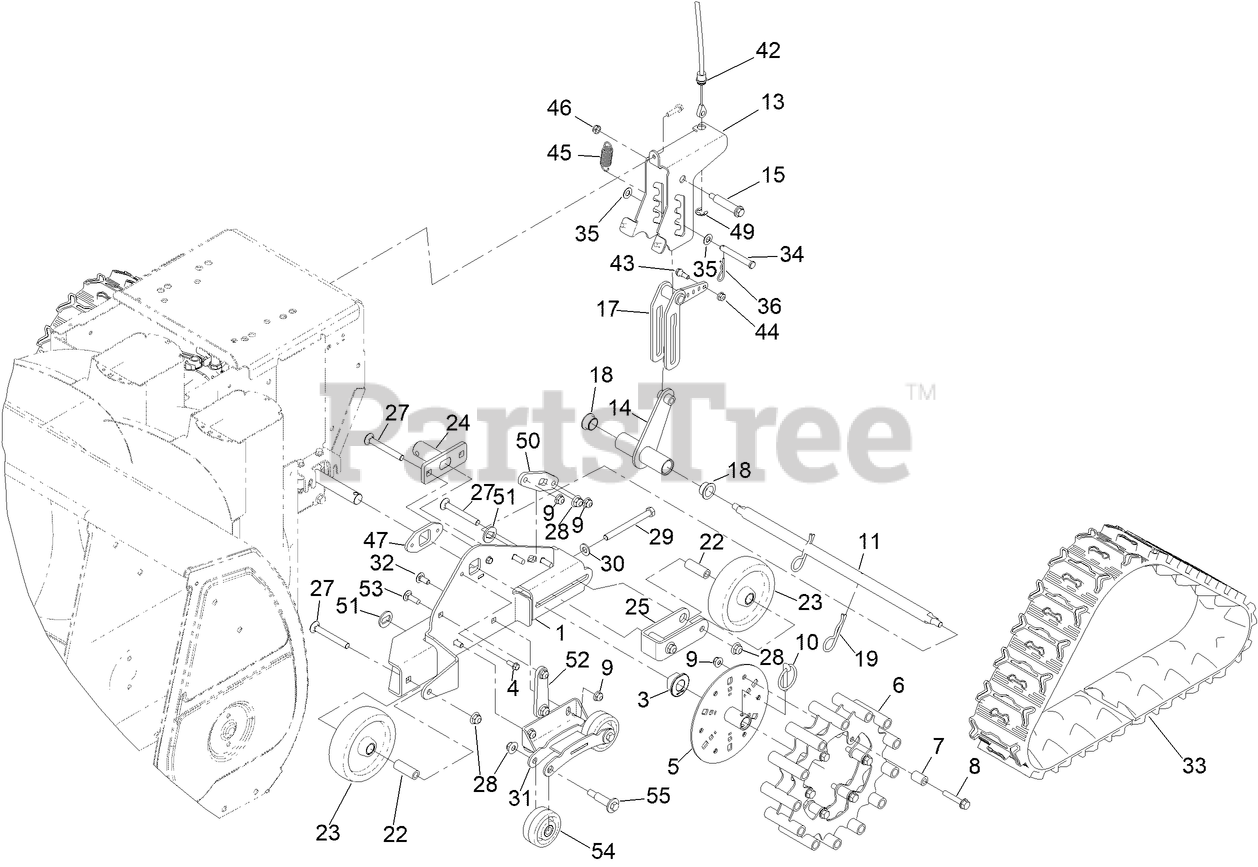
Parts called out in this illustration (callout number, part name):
1	SUPPORT-TRACK, ASM LH
3	BUSHING-AXLE
4	SCREW-HWH
5	HUB-DRIVE, WELD ASM
6	WHEEL-DRIVE, WELD ASM
7	TUBE-SUPPORT
8	SCREW-HHF
9	NUT-HF
10	KLIK PIN ASM
11	BAR-PIVOT
13	BRACKET-HEIGHT, ADJUSTER
14	PIVOT-LINK, WELD ASM
15	BOLT-SHOULDER
17	LATCH ASM, WELDED
18	BUSHING-FLANGE
19	PIN-HAIR
22	BUSHING-TENSIONER
23	WHEEL-BOGEY
24	TENSIONER, WELDED
25	YOKE-BOGEY
27	BOLT-CARRIAGE
28	NUT-HF, NI
29	SCREW-HH
30	WASHER-FLAT
31	SUPPORT-WHEEL, ASM
32	BOLT-CARR
33	TRACK-SNOW
34	PIN-CLEVIS
35	WASHER-THRUST
36	PIN-HAIR
42	CABLE-ADJUST, HEIGHT
43	BOLT-SHOULDER
44	NUT-FLANGE, NI
45	SPRING-EXTENSION
46	NUT-HEX
47	SUPPORT-BUSHING, AXLE
49	RING-RETAINING, EXTERNAL
50	PLATE-BAR, PIVOT
51	WASHER-SPECIAL, D
52	PLATE-SUPPORT
53	BOLT-CARR
54	WHEEL-BOGEY
55	BOLT-SHOULDER
